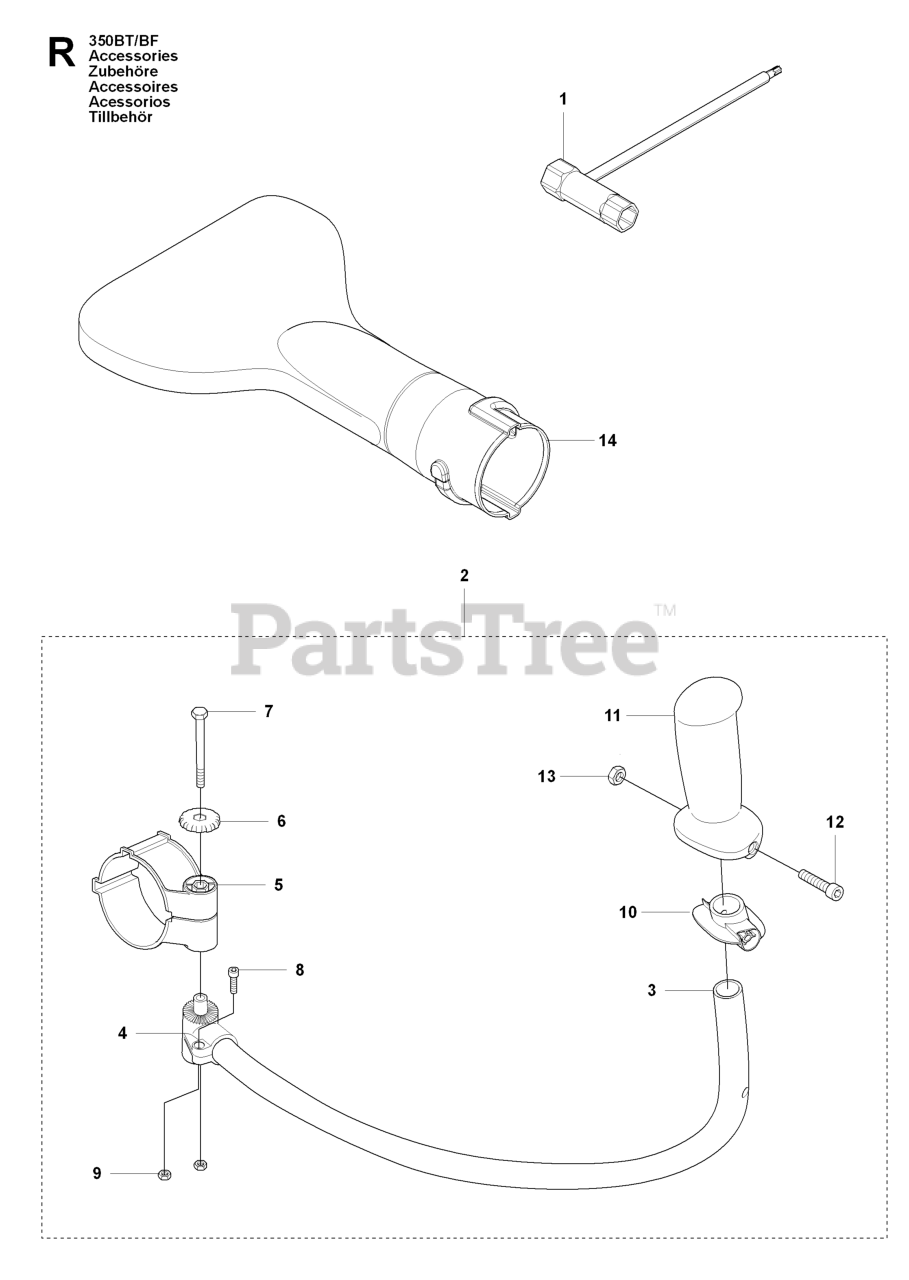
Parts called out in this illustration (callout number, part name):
2	HANDLEBAR ASSY
5	HOLDER TH
8	SCREW MC6S 5X10
14	FLAT NOZZLE
